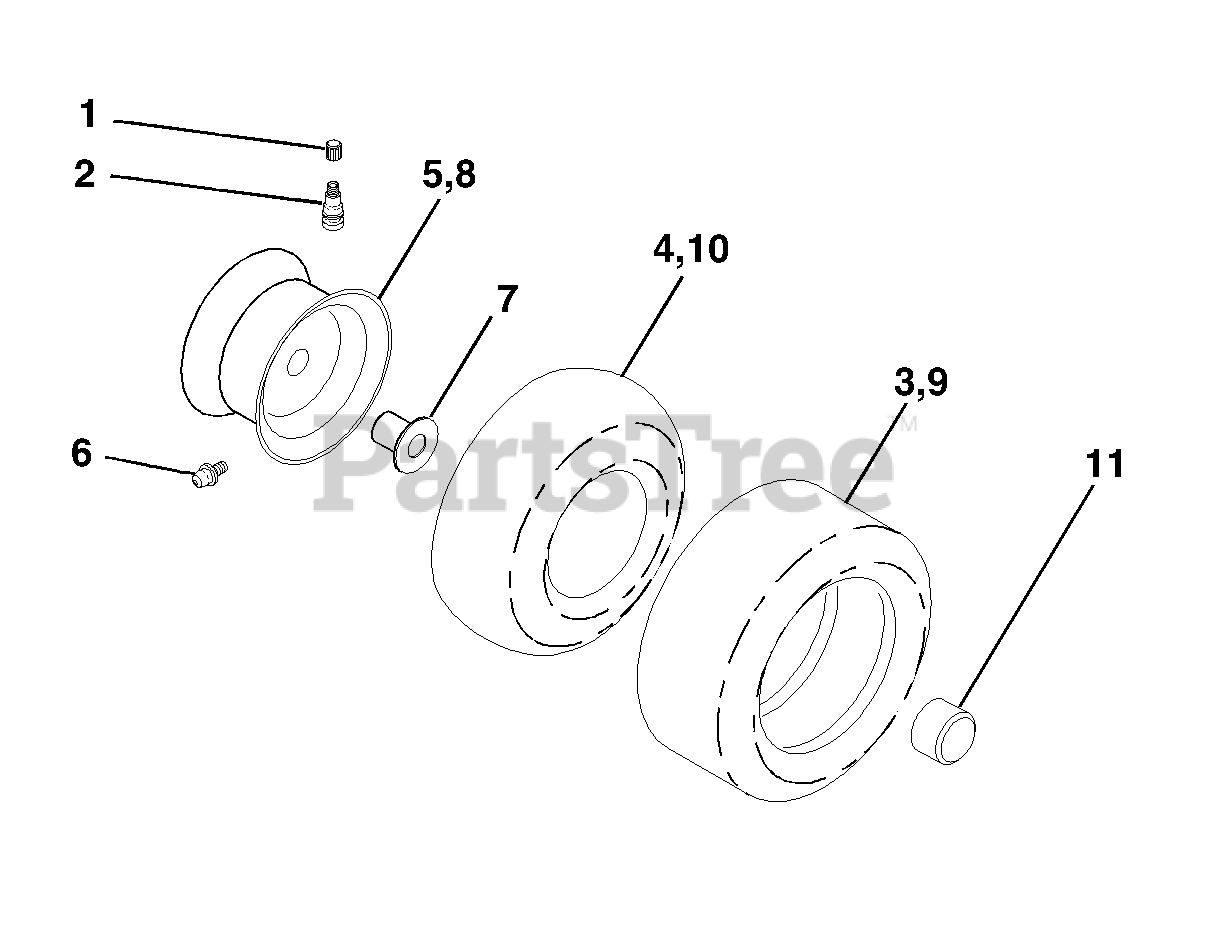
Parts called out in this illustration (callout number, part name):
1	Cap Valve Tire
2	Stem Valve
3	Tire F Ts 15 X 6 0 - 6 Service
4	Tube Front
5	Rim Asm 6" front White Service
6	Fitting Grease
7	Bearing Flange
8	Rim Asm 8" rear White Service
9	Tire R Ts 18x9.5-8 C Service
10	Tube Rear
11	Cap Axle Blk 1 50 X 1 00
